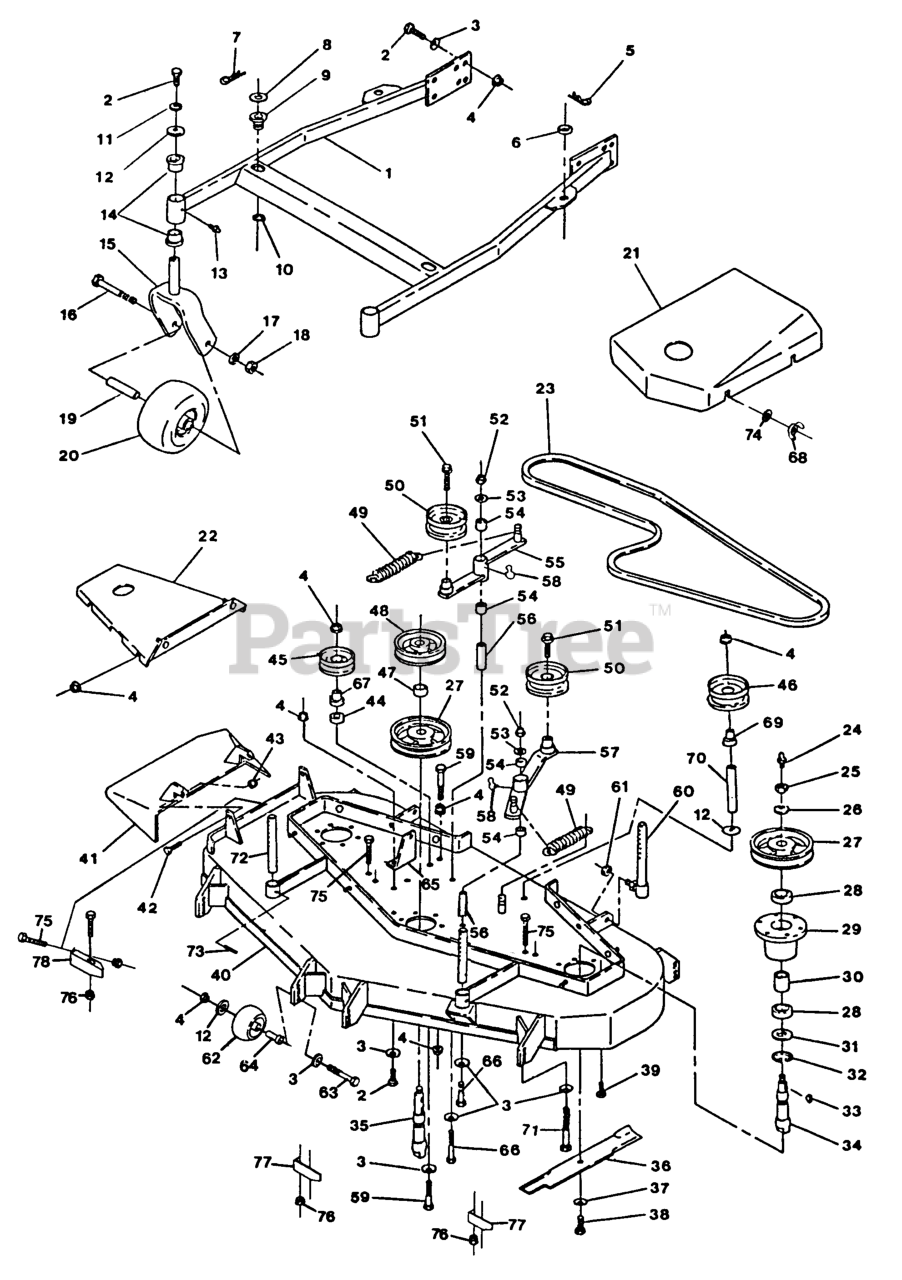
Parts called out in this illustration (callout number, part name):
5	PIN,HAIR COTTER
8	WASHER-FLAT
9	BUSHING-DECK
14	BEARING-FLANGED
23	BELT,BLADE DRIVE
26	WASHER-SPRING
27	SHEAVE,BLADE DRIVE
30	SPACER,BEARING
31	SEAL,MECHANICAL DUST
32	RING,SNAP WLDS N5000-244
34	SPINDLE-OUTER BLADE
35	SPINDLE-CENTER BLADE
37	WASHER-SPRING
39	SCRW,TPTTE HH
41	WLD,CHUTE DISCHARGE
46	PULLEY-IDLER
47	SPACER-TUBE
48	SHEAVE,MOWER DRIVE
49	SPRING-EXTENSION
50	IDLER,PULLEY
54	SLEEVE-BEARING
55	ASM,IDLER ARM
56	BUSHING-PIVOT, IDLER
57	ASM,IDLER ARM
62	ROLLER-SCALP, ANTI
64	BUSHING-ROLLER
65	BRACKET,SPRING ANCHOR
66	SCREW-HH
67	BUSHING-IDLER
68	NUT-WING
69	BUSHING,IDLER
70	SPACER-FENDER
72	ROD,DECK SUPPORT
78	WLD,BAFFLE DISCHARGE
